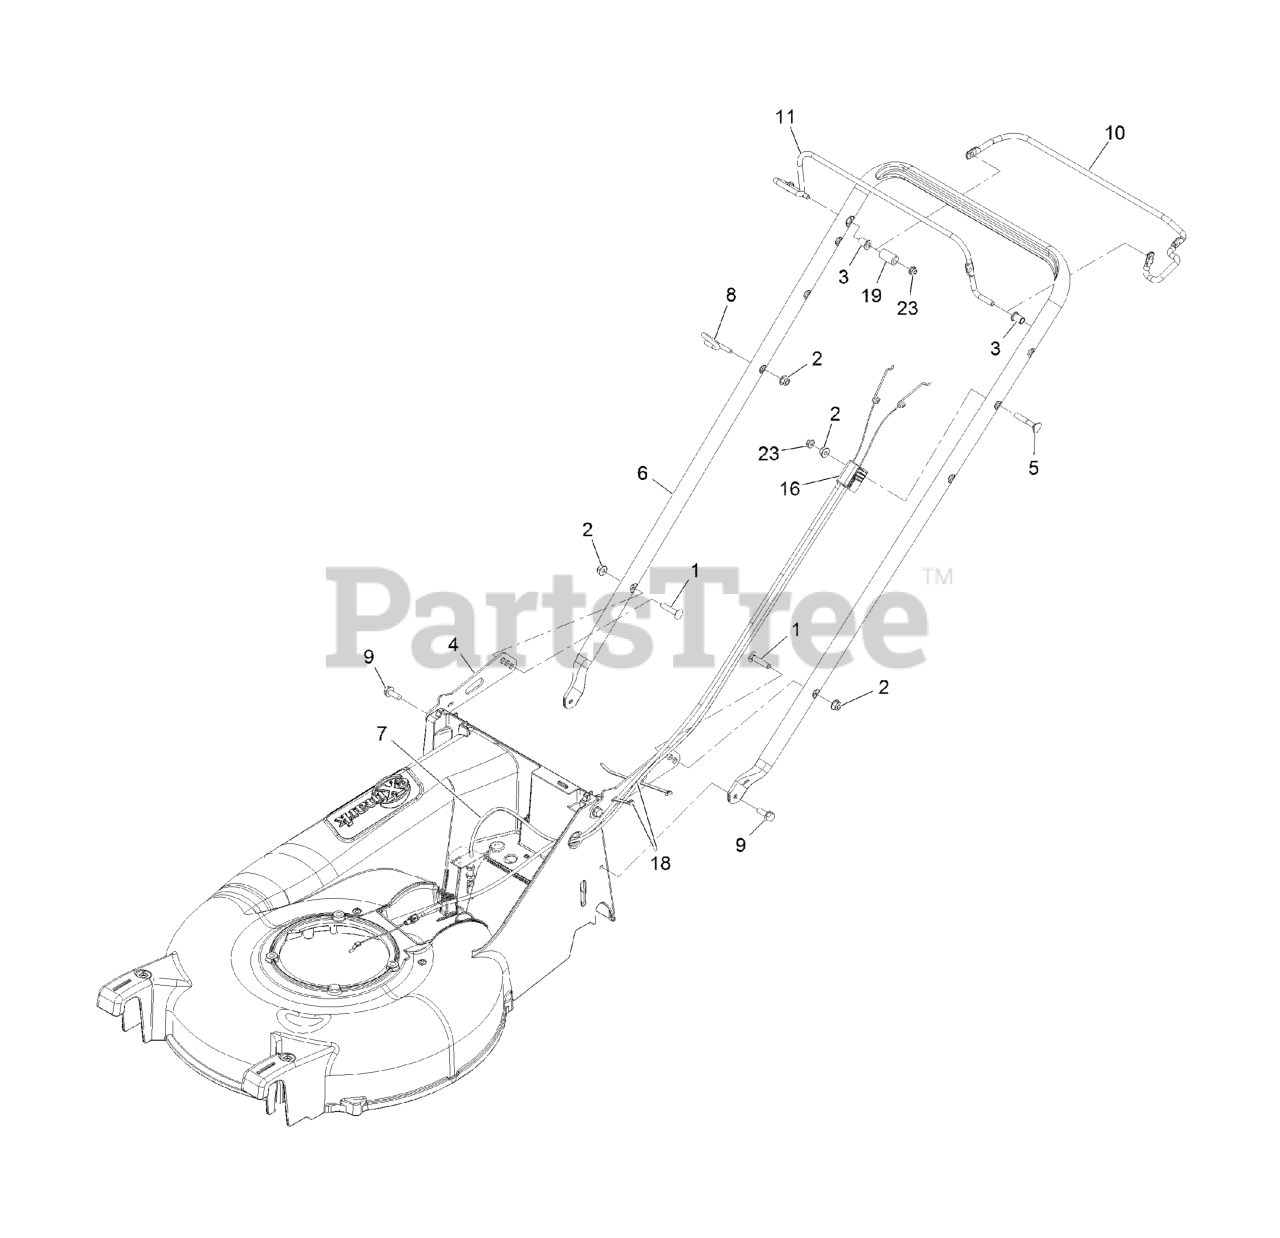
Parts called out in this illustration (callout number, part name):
1	BOLT-CARR
2	NUT-HF, NI
3	BUSHING-HANDLEBAR
4	BRACKET,HANDLEBAR
6	HANDLEBAR-P21
7	CABLE, DRIVE EC21
8	GUIDE,ROPE
9	SCREW-TAPTITE
10	BAIL-DRIVE COATED
16	CABLE-ZONE KAWASAKI
18	TIE-CABLE
